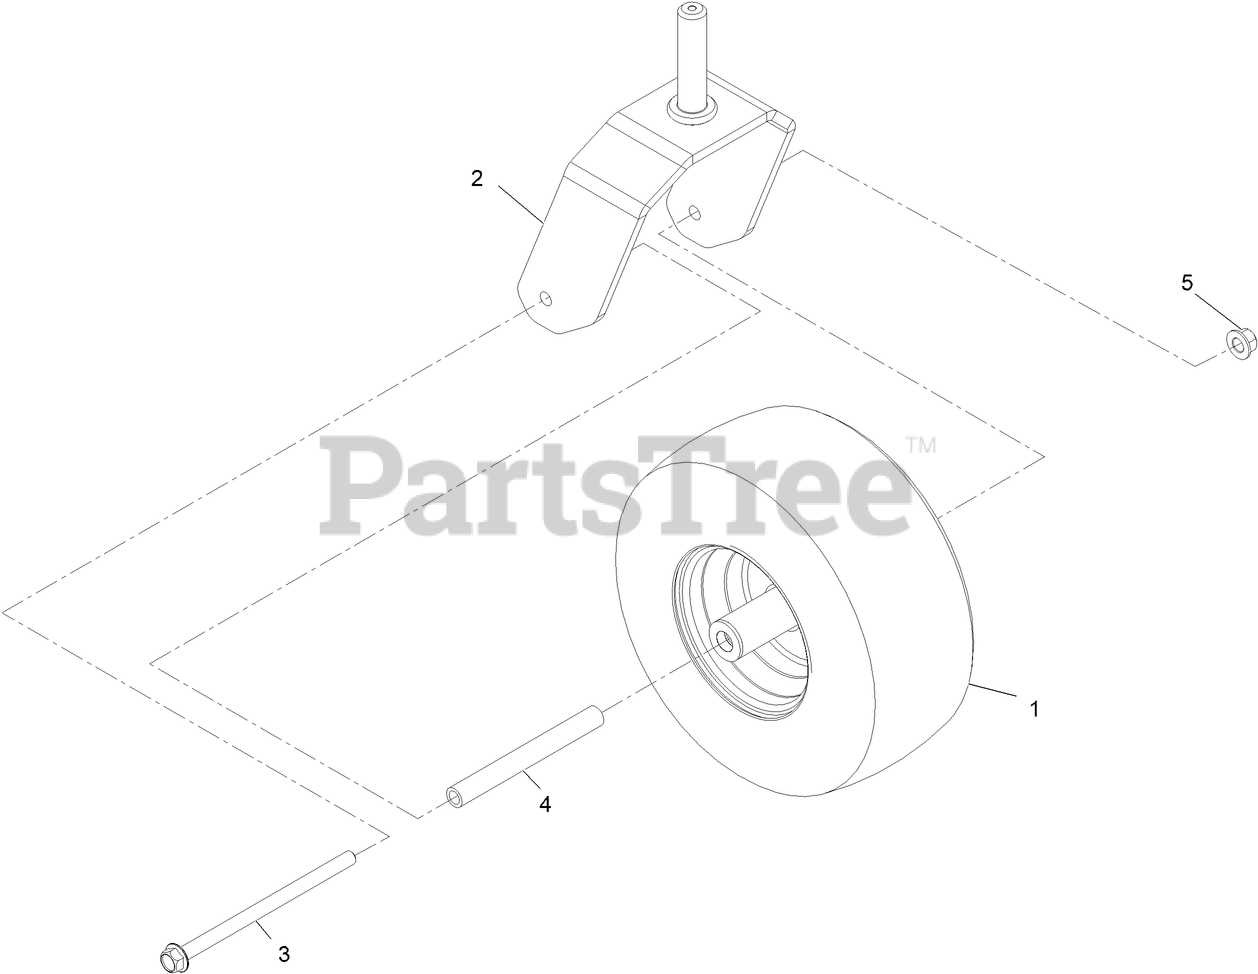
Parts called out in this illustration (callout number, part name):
1	ASM-WHEEL AND TIRE 13X6.50-6
2	CASTER-FORK
3	SCREW-HHF
4	SPANNER-WHEEL, CASTER
5	Nut-Lock 1/2-13
